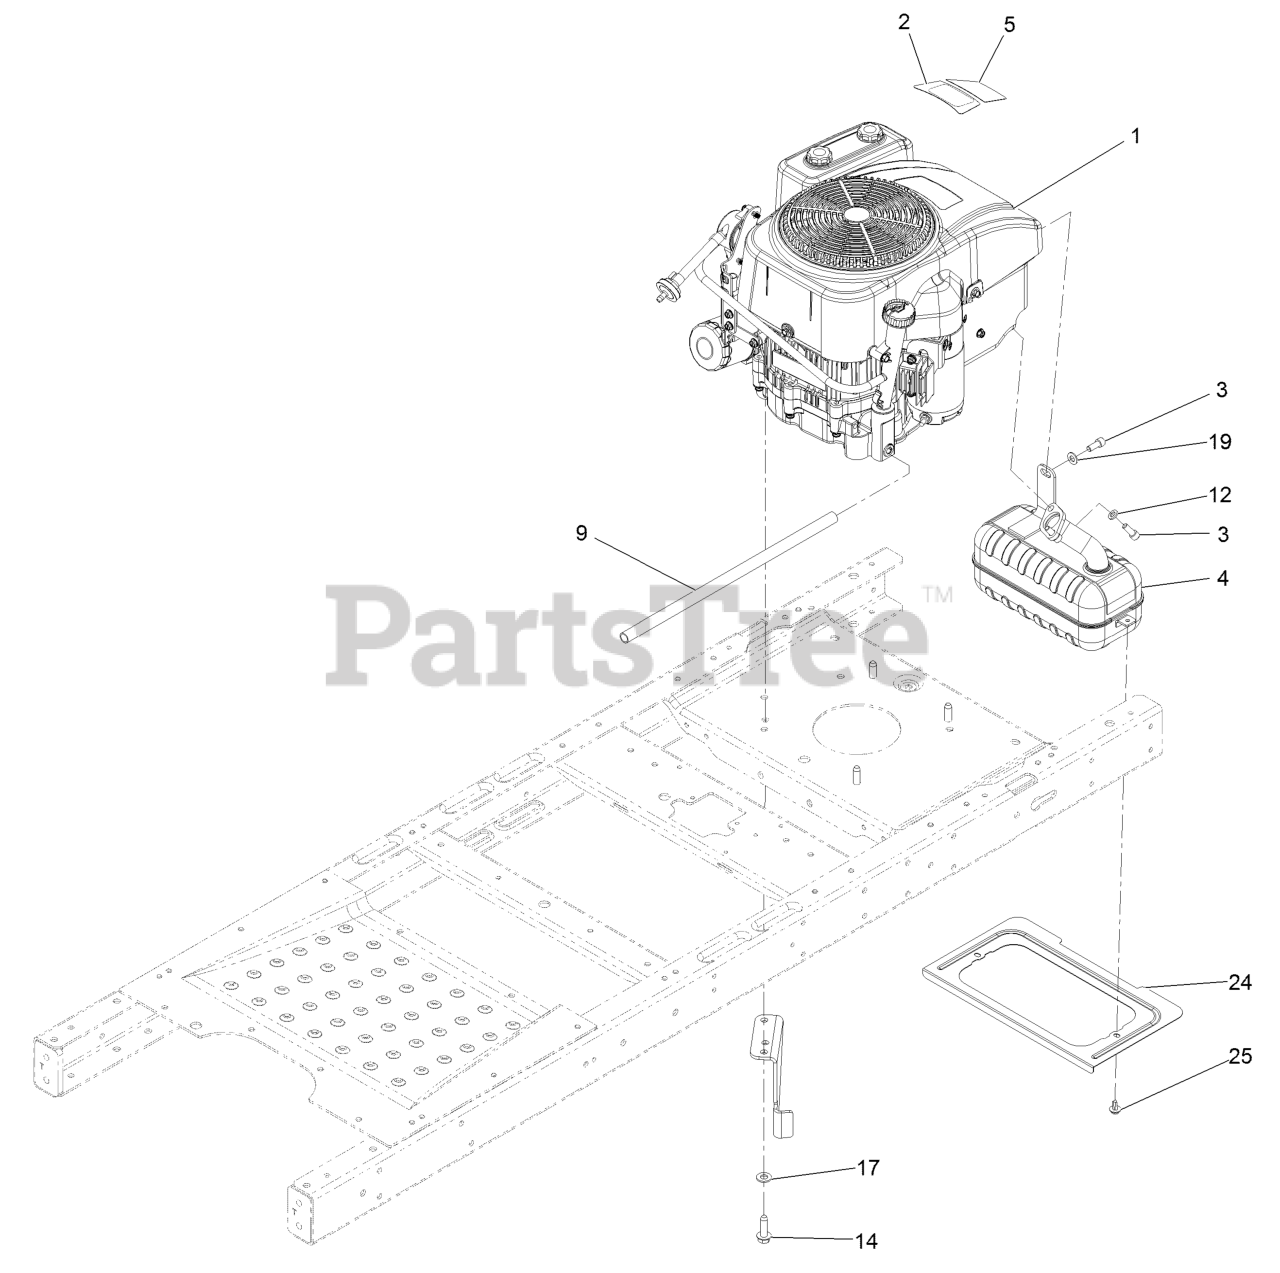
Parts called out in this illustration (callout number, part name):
2	DECAL-ENGINE
3	SCREW-HSH
5	DECAL-ENGINE DISPLACEMENT
9	TUBE-DRAIN, OIL
12	WASHER-LOCK
14	SCREW-THD
17	WASHER-FLAT
19	WASHER-PLAIN
24	SHIELD-HEAT
25	SCREW-HHFTF
